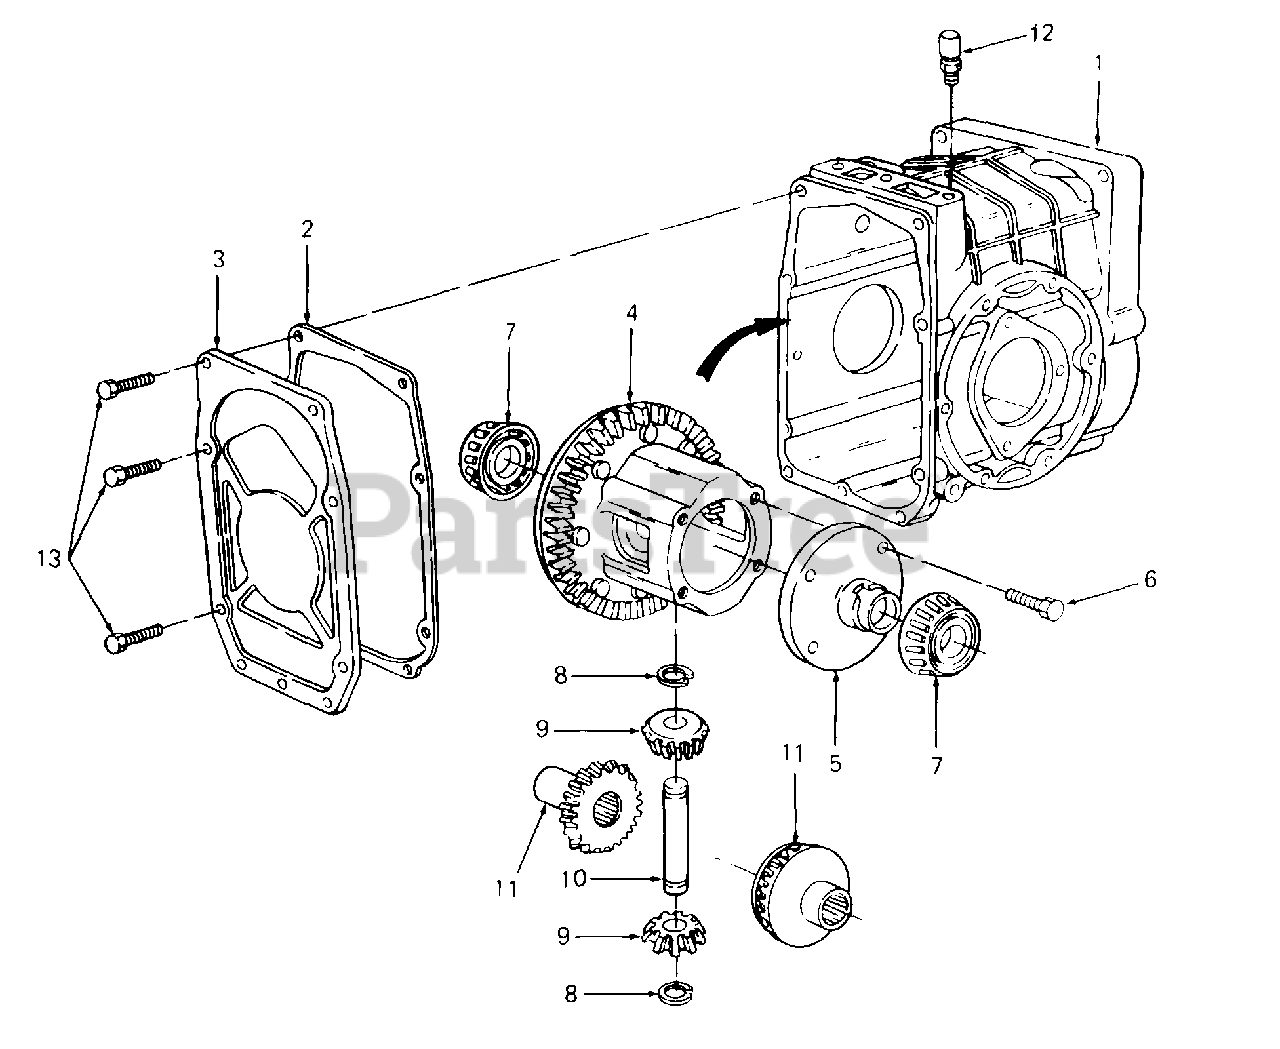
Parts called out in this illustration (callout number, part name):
1	Housing Assy, Rear Axle
2	Gasket, Rear Cover
3	Plate, Rear Cover
4	Gear Assy, Ring w/Case
5	Plate, Differential Flange
6	Screw, Hex Cap, 5/16-18 X 1.25 Lg GR5
7	Cone, Roller Brg
8	Ring, Retaining
9	Gear, Pinion - 10T
10	Shaft, Cross
11	Gear, Side 16T
12	Breather, Housing
13	Bolt, Hex Patch, 3/8-16 X .62 Lg GR5
